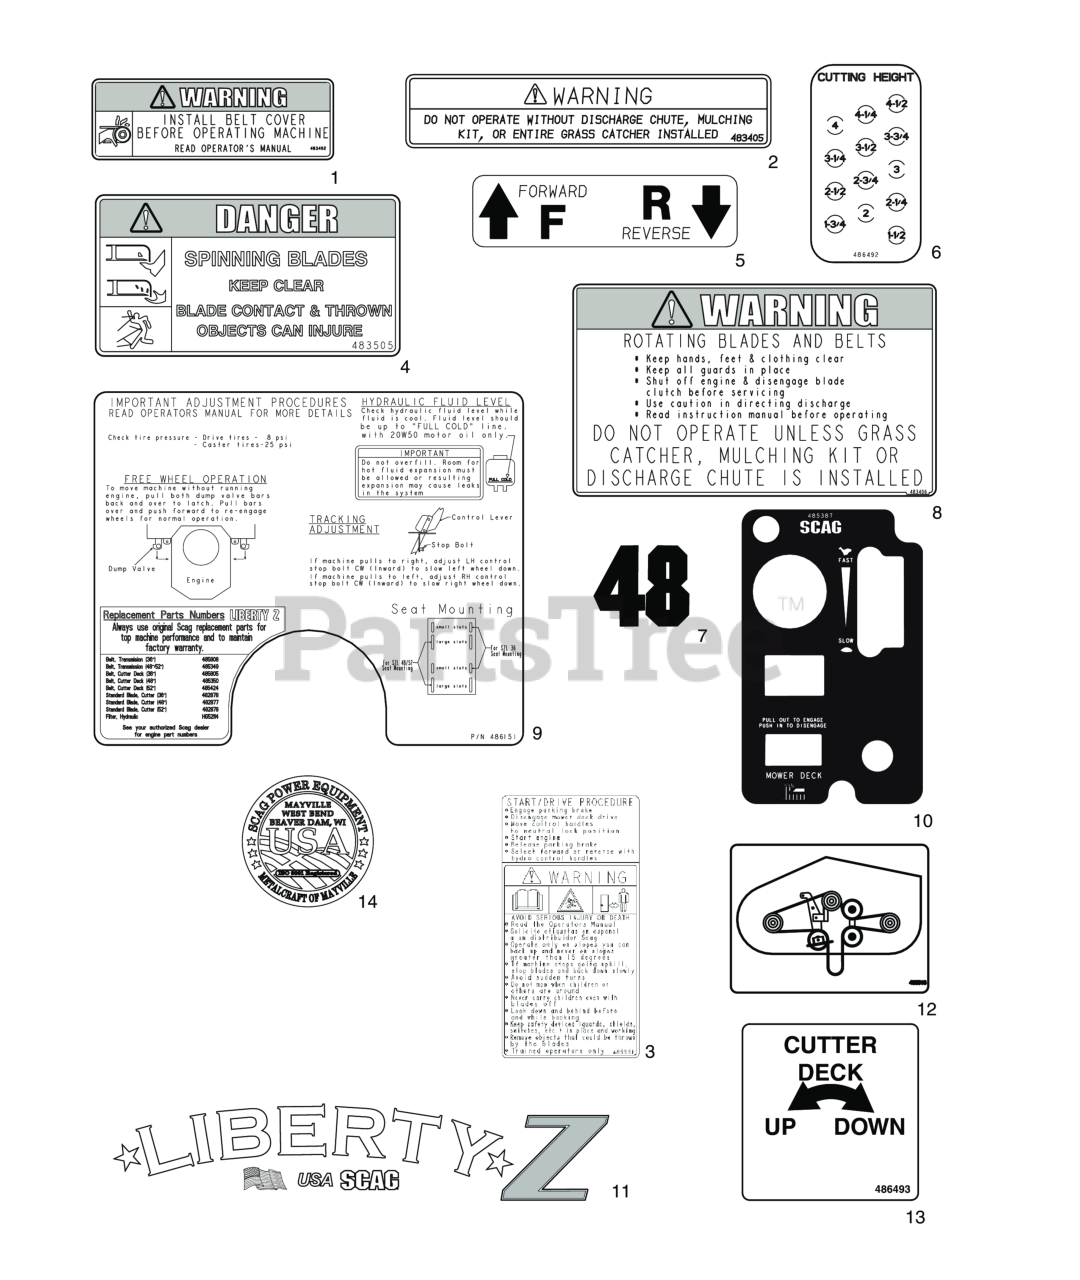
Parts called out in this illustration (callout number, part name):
1	Decal, Warning - Belt Cover
2	Decal, Warning-Discharge
3	Decal, Start/Drive
4	Decal, Spinning Blades
5	Decal, Traction Control
6	Decal, Height of Cut
7	A-Decal-36
8	Decal, Warning - Rotating Blades
9	Decal, Adjustments - SZL
10	Decal, Instrument Panel - SZL (36)
11	Decal. Liberty Z - Fuel Tank
12	Decal, Belt Routing - SZL (36)
13	Decal, Cutter Deck Lift Control
14	Decal, Metalcraft - USA
